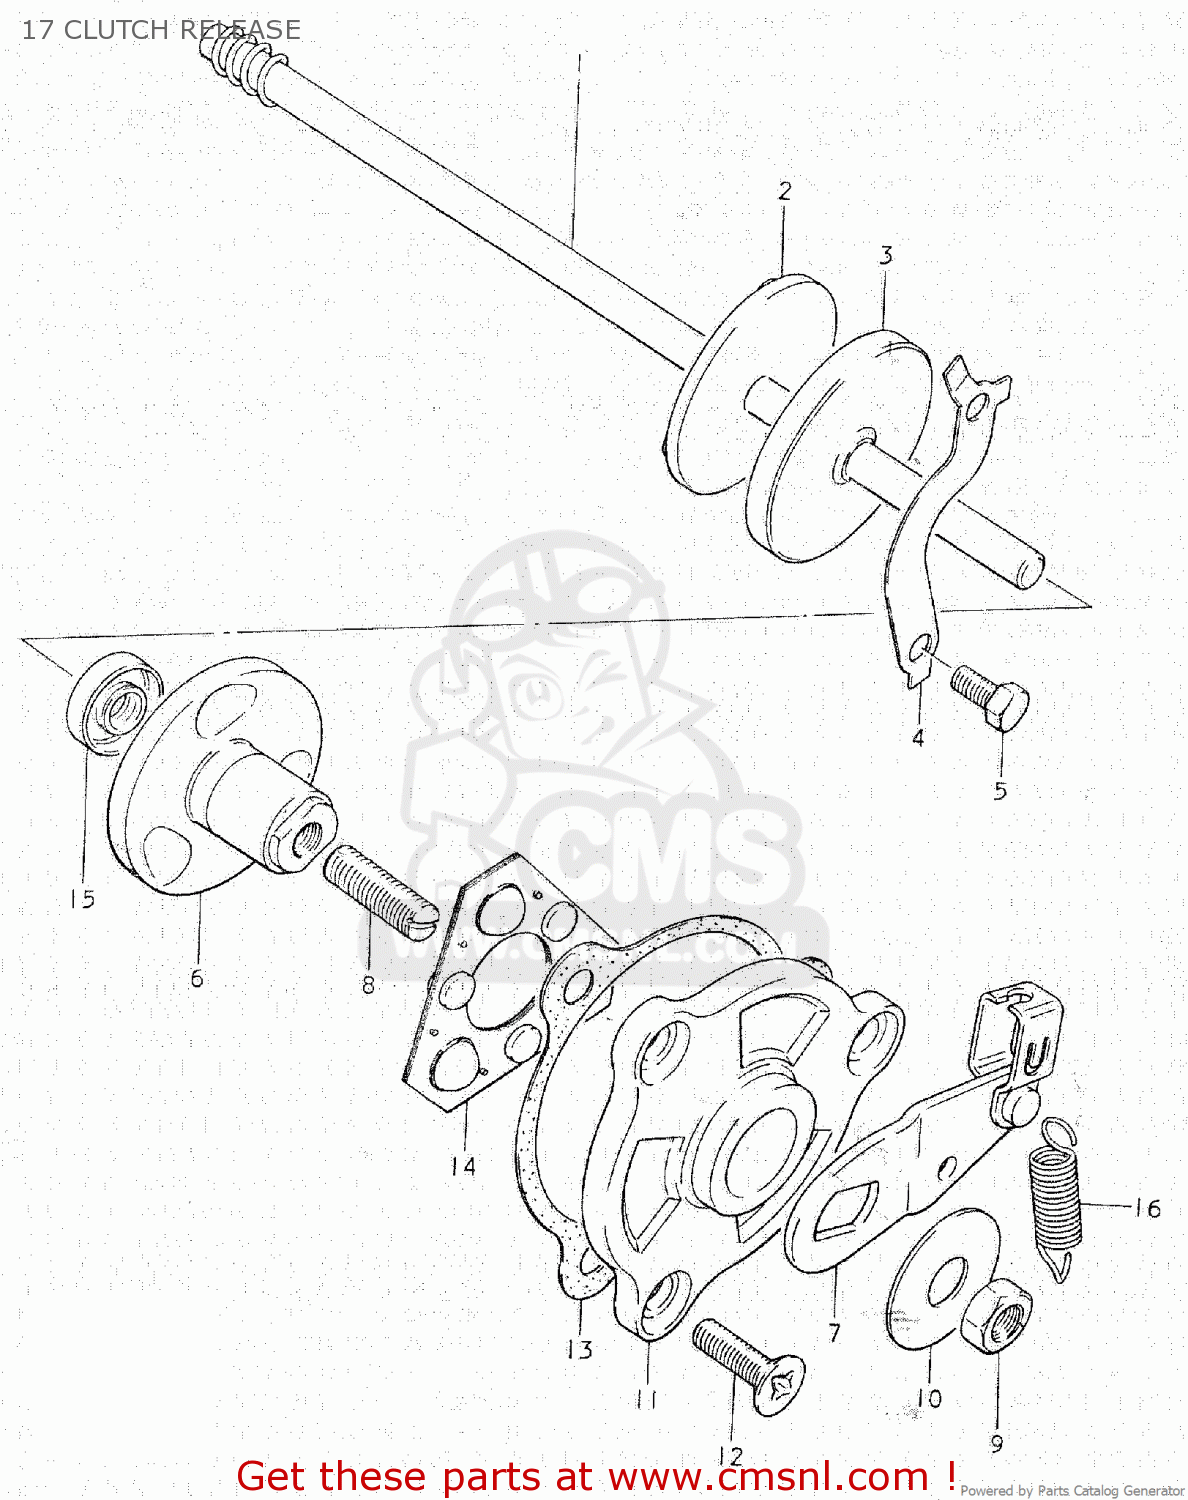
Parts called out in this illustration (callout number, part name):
1	ROD ASSY,CLUTCH RELEASE
2	HOLDER,CLUTCH PUSH ROD
3	SEAL,OIL(8X47X8)
4	RETAINER,CL PUSH ROD OIL SEAL
5	BOLT
6	GUIDE,CLUTCH RELEASE,OUTER
7	ARM,CLUTCH RELEASE
8	SCREW
9	NUT 8MM
10	WASHER(8.5X26X1.2)
11	GUIDE,CLUTCH RELEASE,INNER
12	SCREW
13	GASKET,BALL GUIDE (MCA)
14	BALL,CLUTCH RELEASE
15	SEAL,OIL(8X20X7)
16	SPRING
